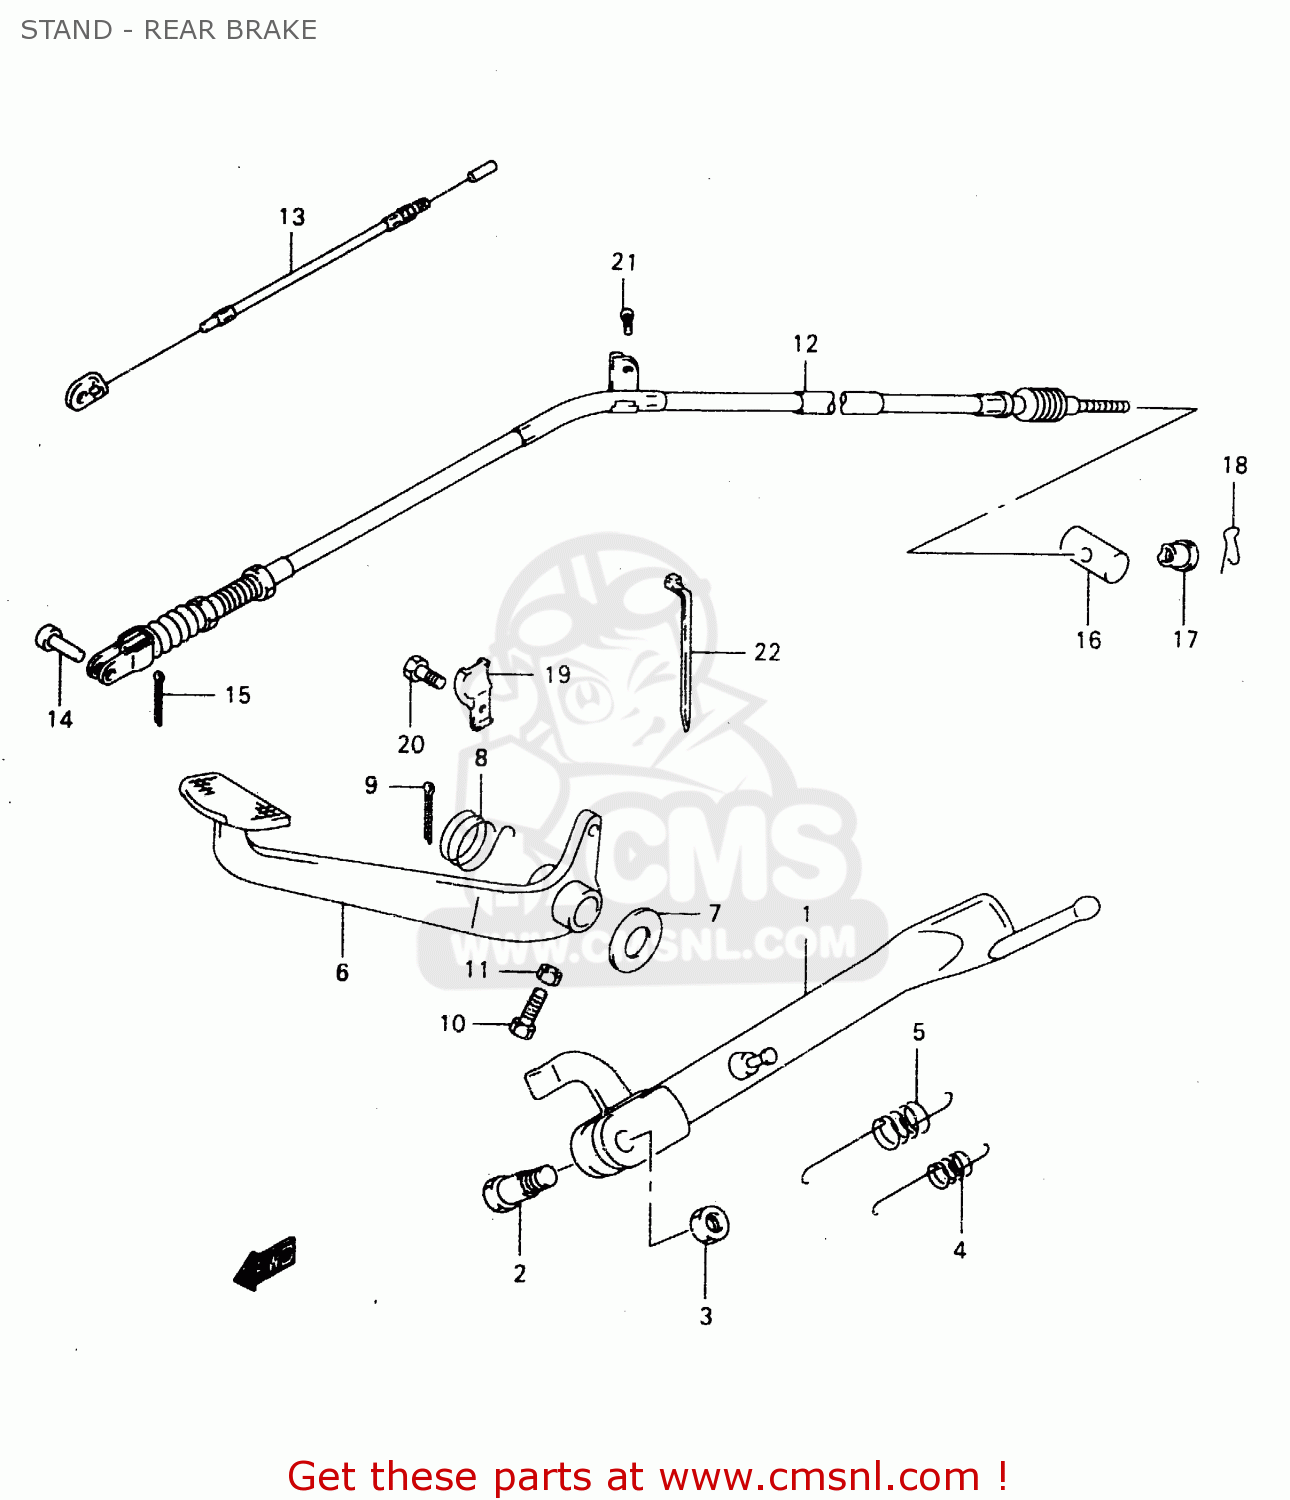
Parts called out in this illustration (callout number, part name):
1	STAND,PROP
2	BOLT(10X34)
3	NUT
4	SPRING
5	SPRING
6	PEDAL,BRAKE
7	WASHER(16.5X22X1)
8	SPRING
9	COTTER PIN
10	BOLT
11	NUT
12	CABLE,RR BRAKE
13	CABLE,STOP LAMP SWITCH
14	PIN(L:17.5)
15	PIN
16	PIN(13X18)
17	NUT
18	CLIP
19	GUIDE,RR BRAKE CABLE
20	BOLT
21	BOLT,OIL FILLE
22	CLAMP(L:145)
